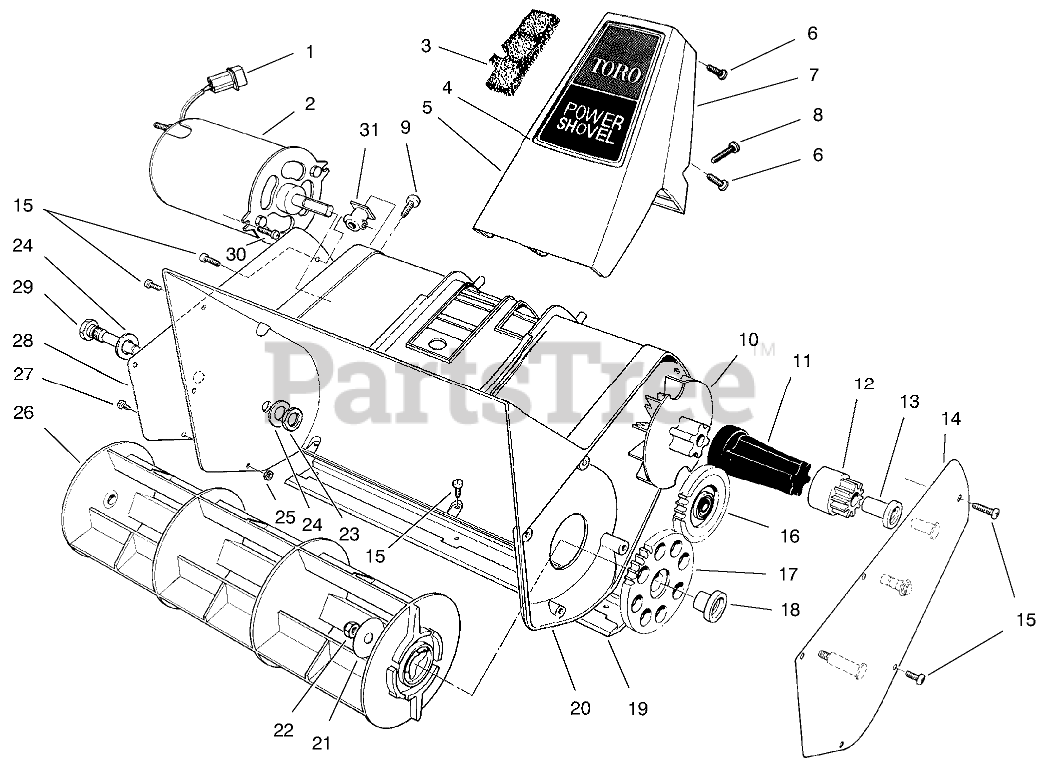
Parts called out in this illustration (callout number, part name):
1	HSG PIN CONNECTOR
2	Motor-(Incl. ref.# 1)
3	FOAM FILTER
4	DECAL-POWER SHOVEL
5	FRONT HANDLE SUPPORT
6	SCREW-PPH
7	HANDLE SUPPORT BACK
8	SCREW-PPH
9	#10-10X3/4 PLASCREW
10	FAN, POWER SHOVEL
11	DRIVE COUPLING
12	Drive Gear (Incl. ref.# 13)
13	BUSHING, DRIVE GEAR
14	Gear Carrier
15	SCREW
16	IDLER GEAR ASM
17	Rotor Gear Assembly (Incl. ref.# 18)
18	BUSHING, ROTOR GEAR
19	1200 SCRAPER, 12"
20	Housing
21	ROTOR WASHER
22	NUT-LOCK, NI
23	NUT-LOCK, CONE
24	WASHER-FLAT
25	NUT-LOCK
26	ROTOR
27	SCREW-PPH
28	RT. SIDE COVER (RAW)
29	ROTOR PIN
30	SCREW-PPH
31	MOUNTING BLOCK
